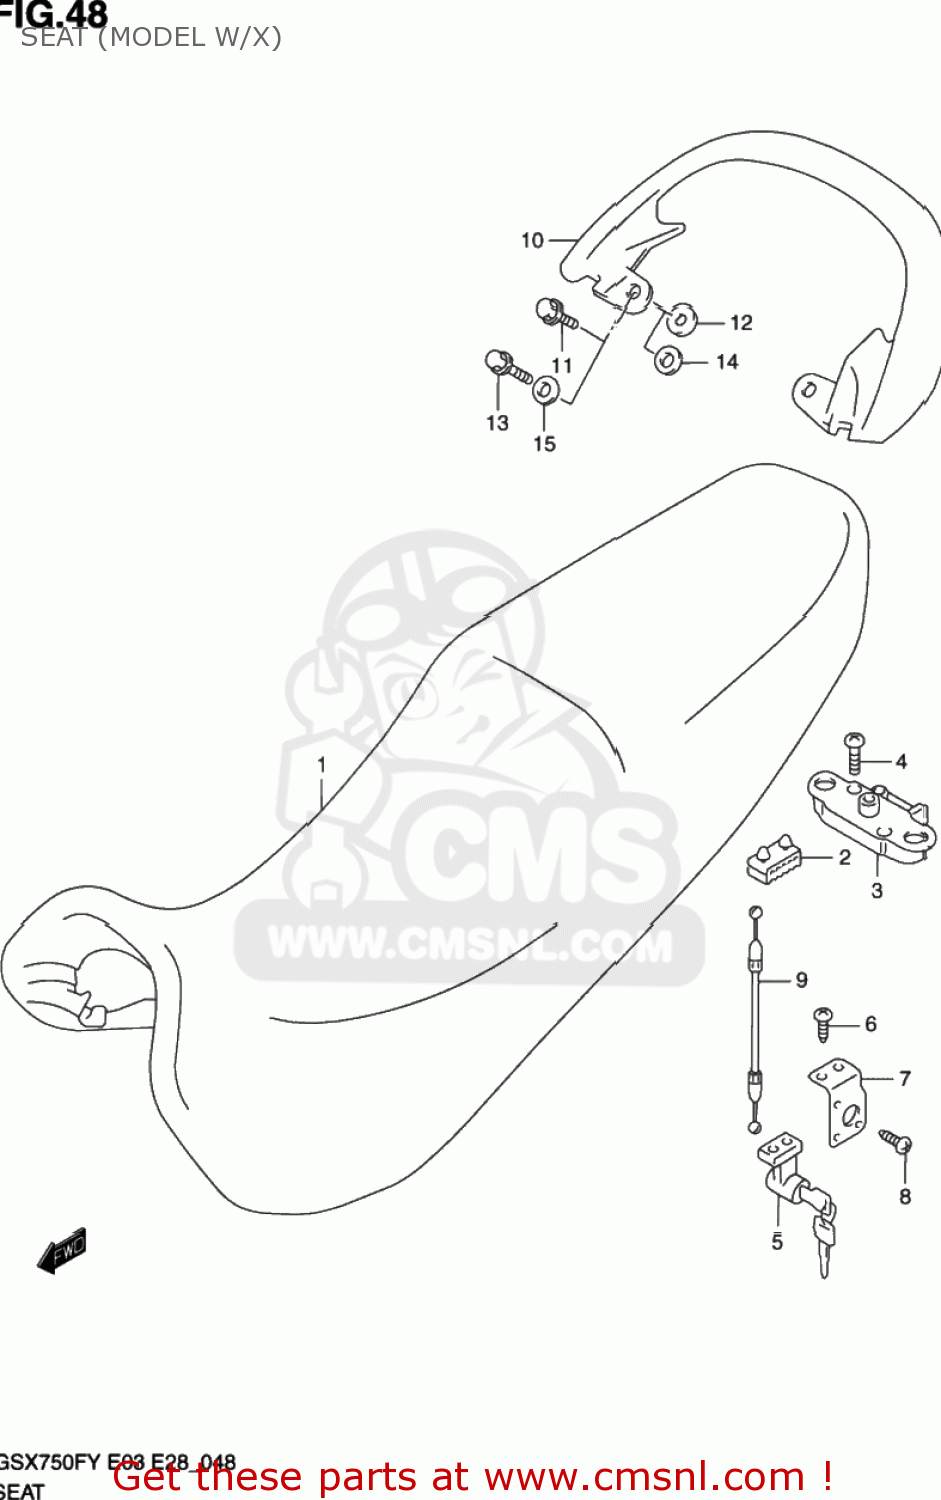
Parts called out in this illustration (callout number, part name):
1	SEAT ASSEMBLY
2	CUSHION,SEAT(40X20X15)
3	BRACKET,SEAT SUPPORT,RIGHT
4	SCREW
5	LOCK SET,SEAT
6	BOLT
7	BRACKET,SEAT LOCK
8	SCREW
9	CABLE,SEAT LOCK
10	HANDLE,PILLION RIDER
11	BOLT
12	CUSHION
13	BOLT
14	CUSHION,RIDER HNDL(17X24X1.5)
15	WASHER(8.5X24X2.3)
